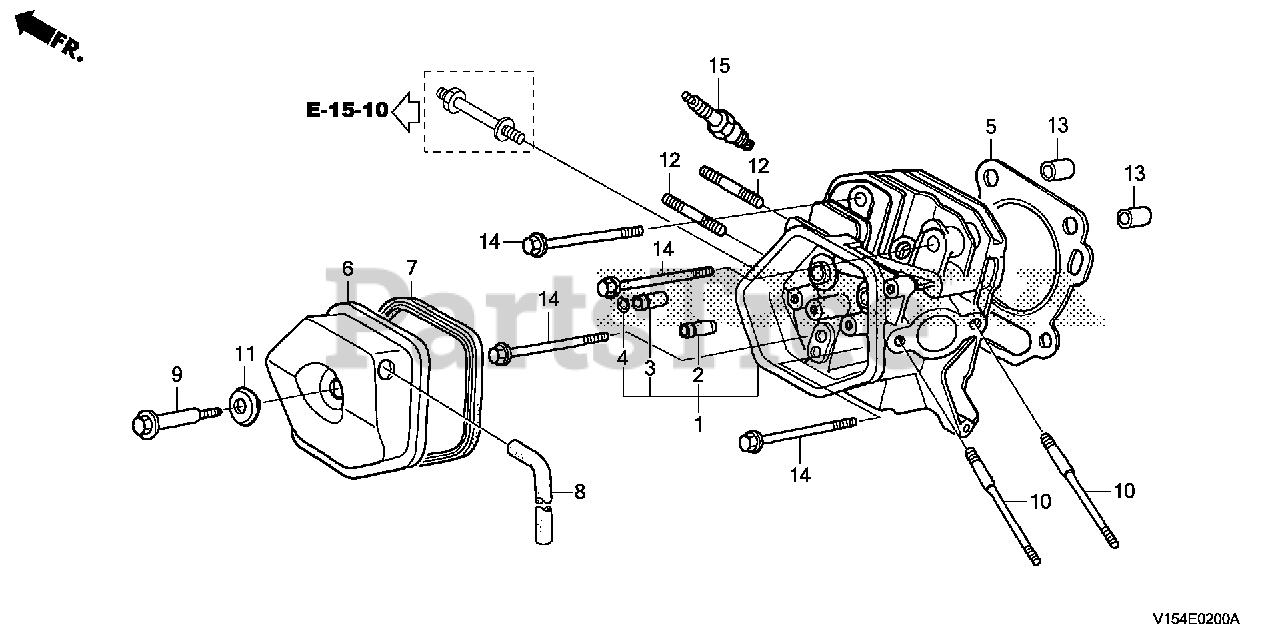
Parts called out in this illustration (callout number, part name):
1	CYLINDER HEAD
2	GUIDE, VALVE (OVER SIZE)
3	GUIDE, EX. VALVE (OVER SIZE)
4	CLIP, VALVE GUIDE
5	GASKET, CYLINDER HEAD (NIPPON LEAKLESS)
6	COVER, HEAD
7	GASKET, HEAD COVER
8	TUBE, BREATHER
9	BOLT, HEAD COVER
10	BOLT, STUD (8X134.5)
11	WASHER, HEAD COVER
12	BOLT, STUD (8X32)
13	PIN, DOWEL (12X20)
14	BOLT, FLANGE (10X80)
15	SPARK PLUG (BPR5ES) (NGK)
15	SPARK PLUG (W16EPR-U) (DENSO)
